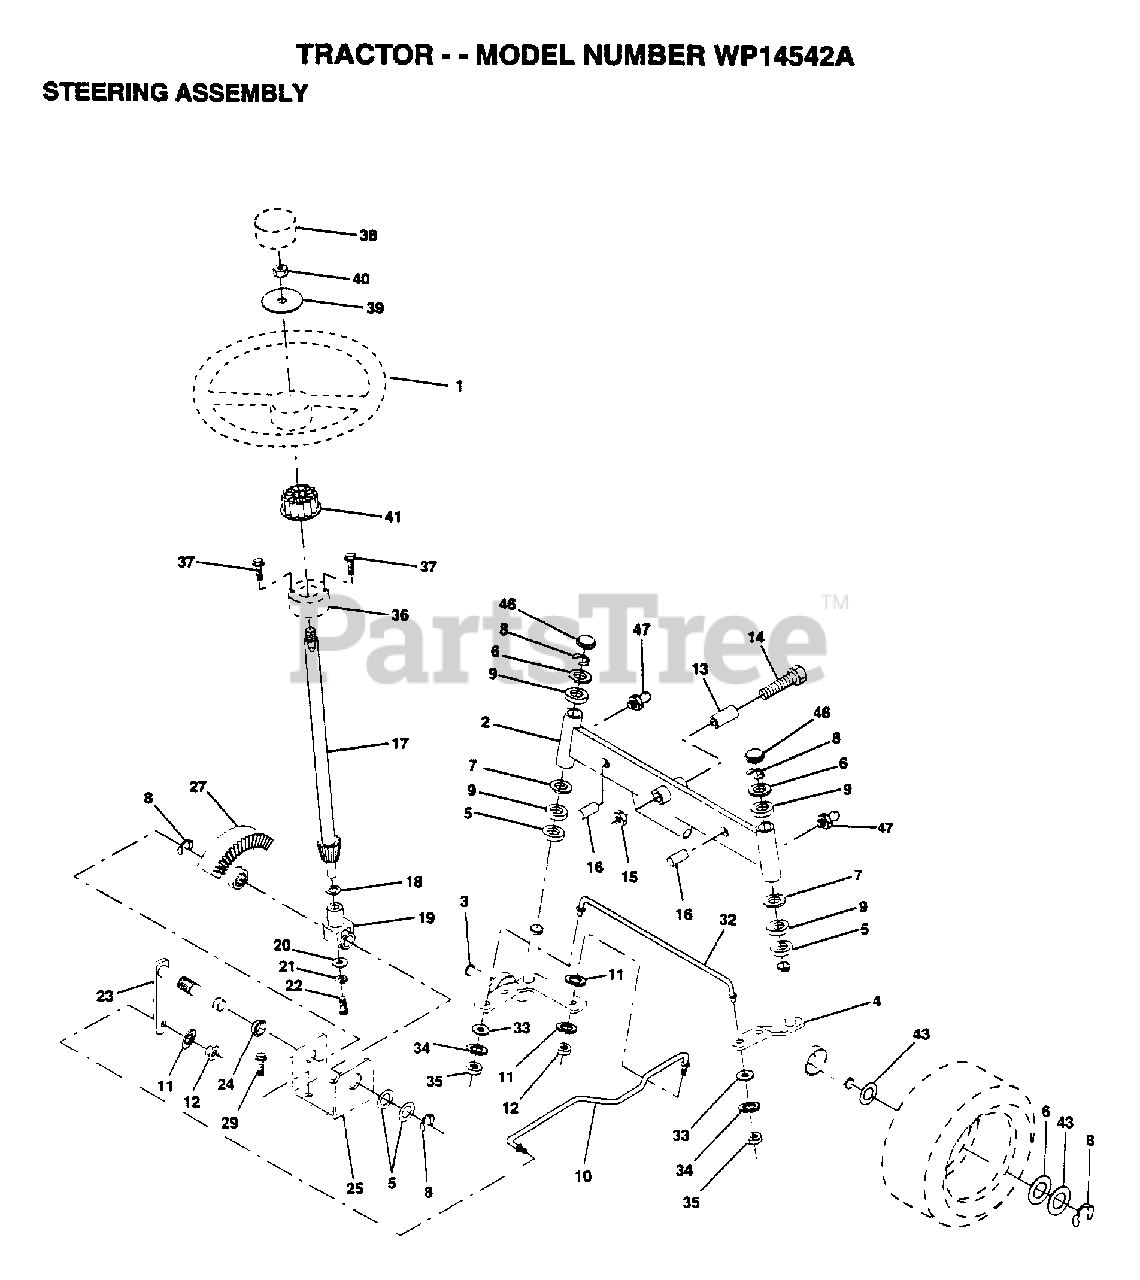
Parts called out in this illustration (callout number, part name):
2	AXLE ASM FRONT
3	SPINDLE LH
4	SPINDLE RH
5	WASHER .T
6	WASHER
7	WASHER
8	RING
9	COL. SRTG. BEAR.
11	LOCKWASHER
13	BEARING
14	BOLT HEX 5/8-11
15	"NUT-LOC,FLANGE LT"
16	AXLE PIN
17	STEERING SHAFT
18	THRUST WASHER
19	SUPPORT.SHAFT
21	LOCKWASHER
22	"SCREW,SPECIAL"
24	NYLINER T
25	"BRKT,STEERING"
27	GEAR SECTOR
29	SCREW
32	TIE ROD
33	WASHER M
34	LOCKWASHER
35	NUT.LOCK.5/16-24
36	BUSHING.STRG.3/4
37	SCREW.10-24X1/2
38	"INSERT,STR WHEEL"
39	WASHER
41	ADAPTER LT
43	WASHER
46	CAP
47	ZERK M
